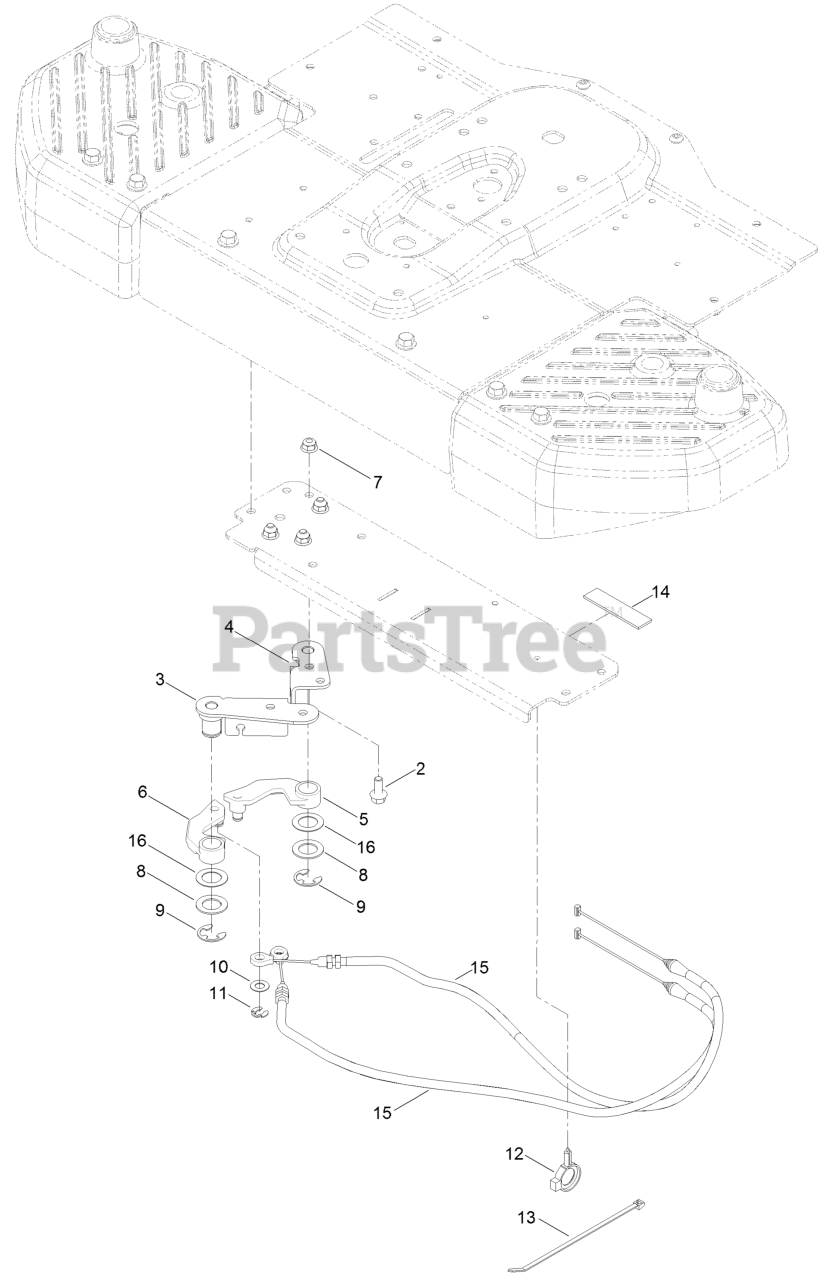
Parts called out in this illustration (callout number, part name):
2	SCREW-HHF
3	CABLE BRACKET ASM
4	CABLE BRACKET ASM
5	ARM-CABLE, RH
6	ARM-CABLE, LH
7	NUT-HF, NI
8	WASHER-THRUST
10	WASHER-THRUST
11	RING-RETAINING
12	CLAMP-HOSE
13	TIE-CABLE
14	STRIP-SEAL
15	CABLE-STEERING
16	WASHER-THRUST
